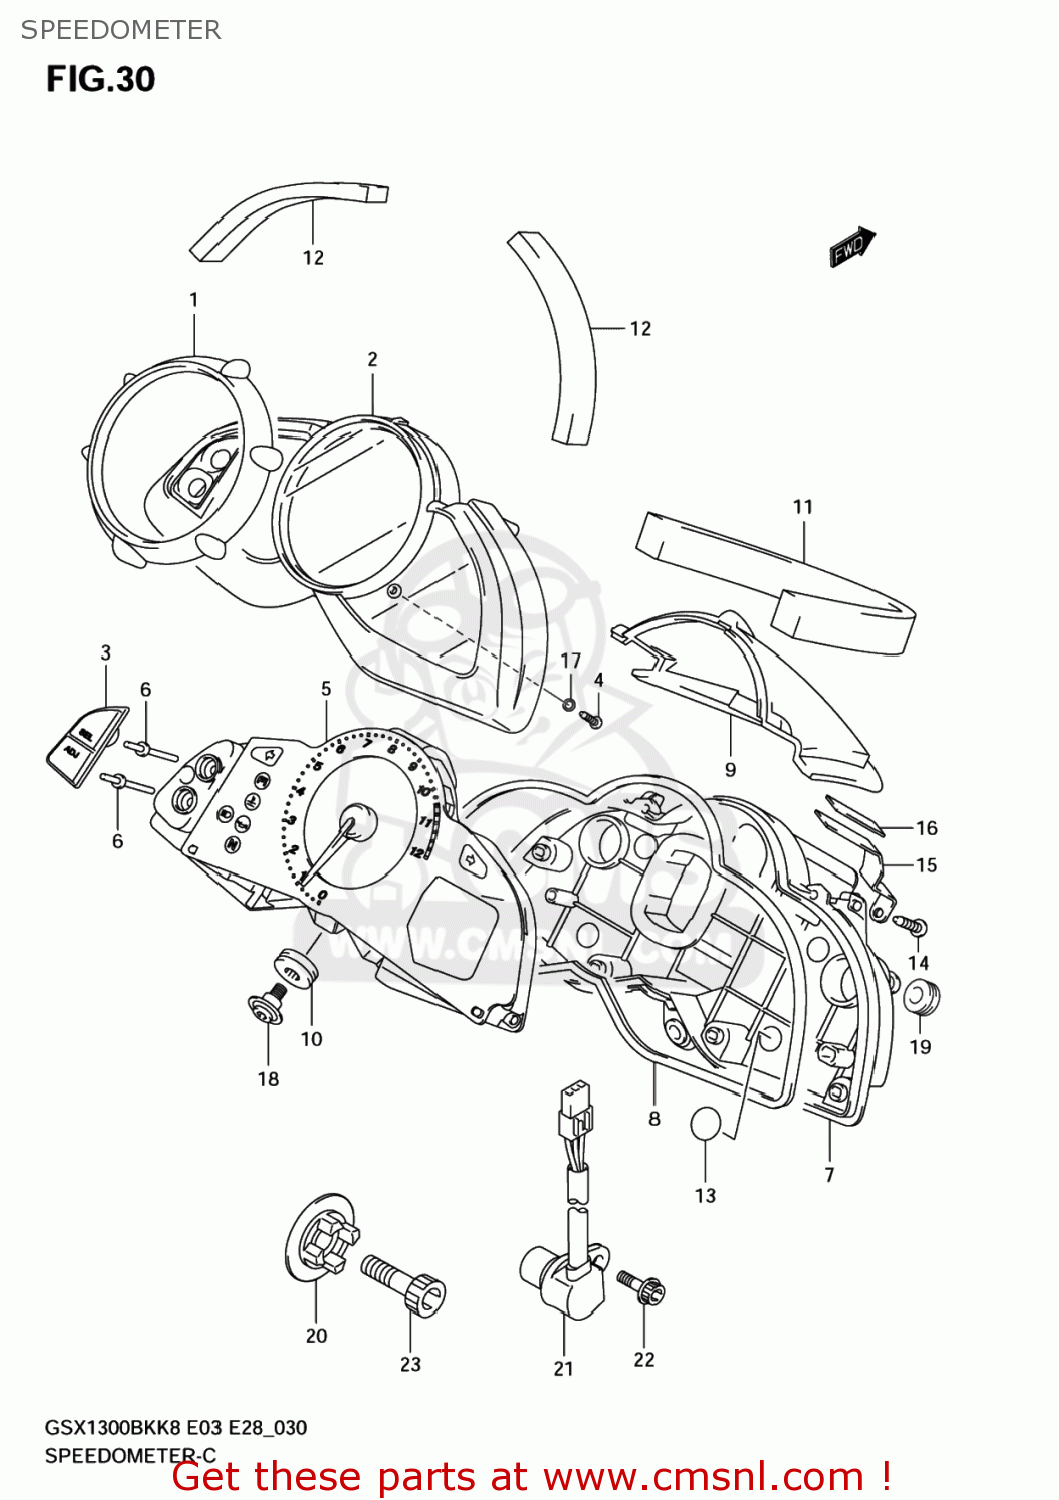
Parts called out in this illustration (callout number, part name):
1	RING
2	CASE,UPR
3	COVER
4	SCREW(3X10)
5	SPEEDOMETER
6	KNOB,SPEEDOMETER
7	CASE,LWR
8	PACKING (NAS)
9	COVER,SPEEDOMETER
10	CUSHION
11	CUSHION NO.1
12	CUSHION NO.2
13	SEAL
14	SCREW(3X12)
15	HOLDER,SPEEDOMETER
16	CUSHION,HOLDER
17	SEAL,WASHER
18	SCREW,SPEEDOMETER
19	CUSHION
20	ROTOR,SPEED
21	SENSOR,SPEED
22	BOLT
23	BOLT
